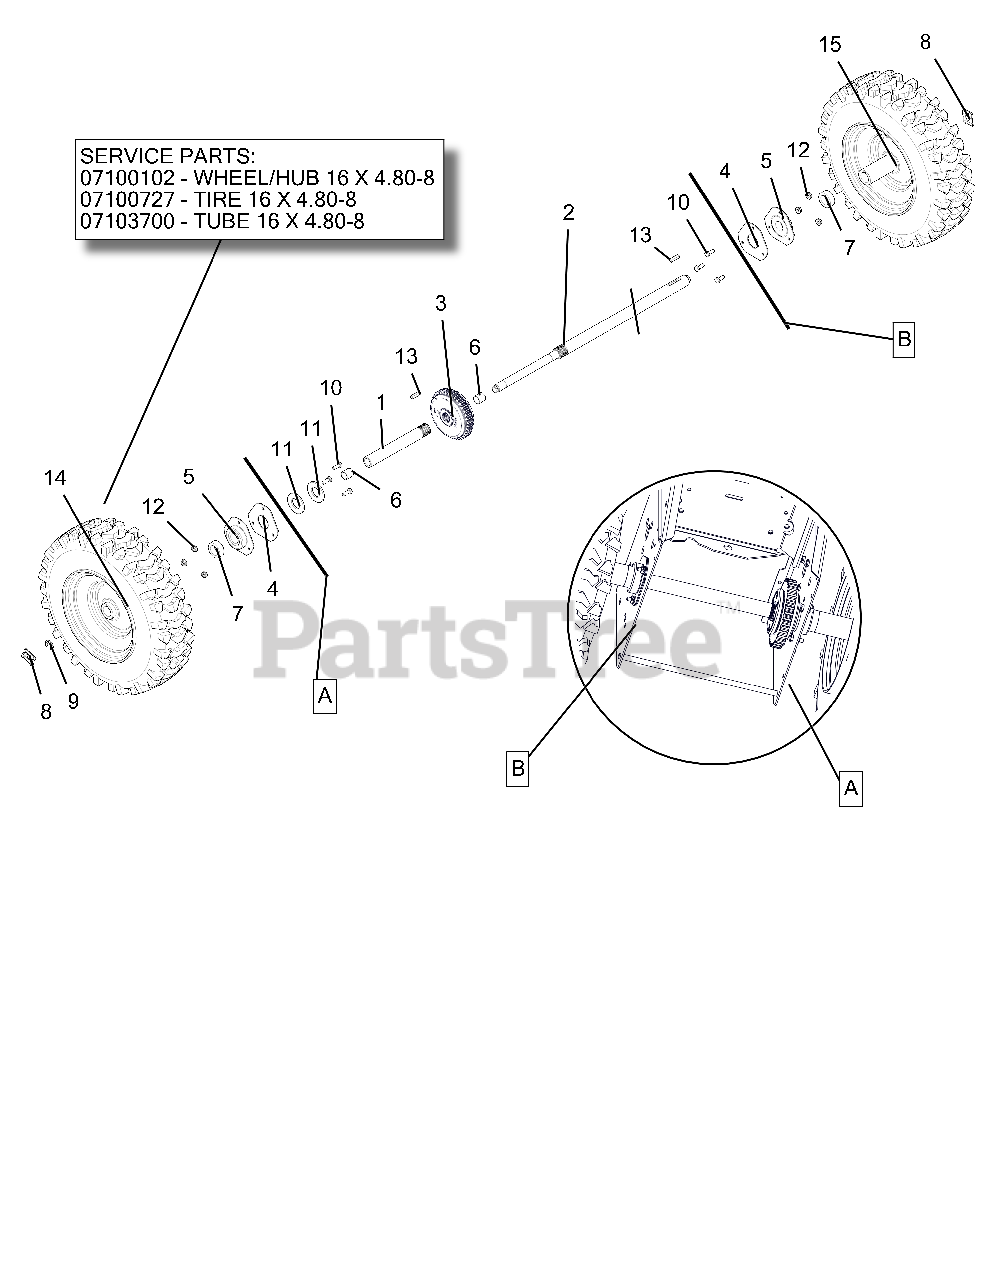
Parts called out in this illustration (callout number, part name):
1	AXLE, SHORT-PRO AUTO DIFF
2	AXLE, LONG-PRO AUTO DIFF
3	DIFFERENTIAL, AUTOMATIC
4	PLATE, BEARING SPACER
5	BRG-FLG 1.003/1.000 3 BOLT
6	BSHG-SLV .706X.764X.75 BRZ
7	SPACER, PRO AXLE BEARING
8	CLIP, SNAP .625 DIA
9	RG-RTNG-EXT .625X.042
10	@BLT-HEX .25-20X.75 GR5 YWZC
11	WSHR-FL-STL- 1.062X2.0X.134 YZ
12	@NUT-LK-CTR-FLG .25-20 YWZC
13	KEY-RECT .25X.188X1.00
14	TIRE/WHEEL,RH 16X4.8-8 DIFF T2
14	HUB, WHEEL - 16X4.8-8 DIFF
14	TIRE, 4.80-8 K478
14	TUBE
15	TIRE/WHEEL,LH 16X4.8-8 DIFF T2
